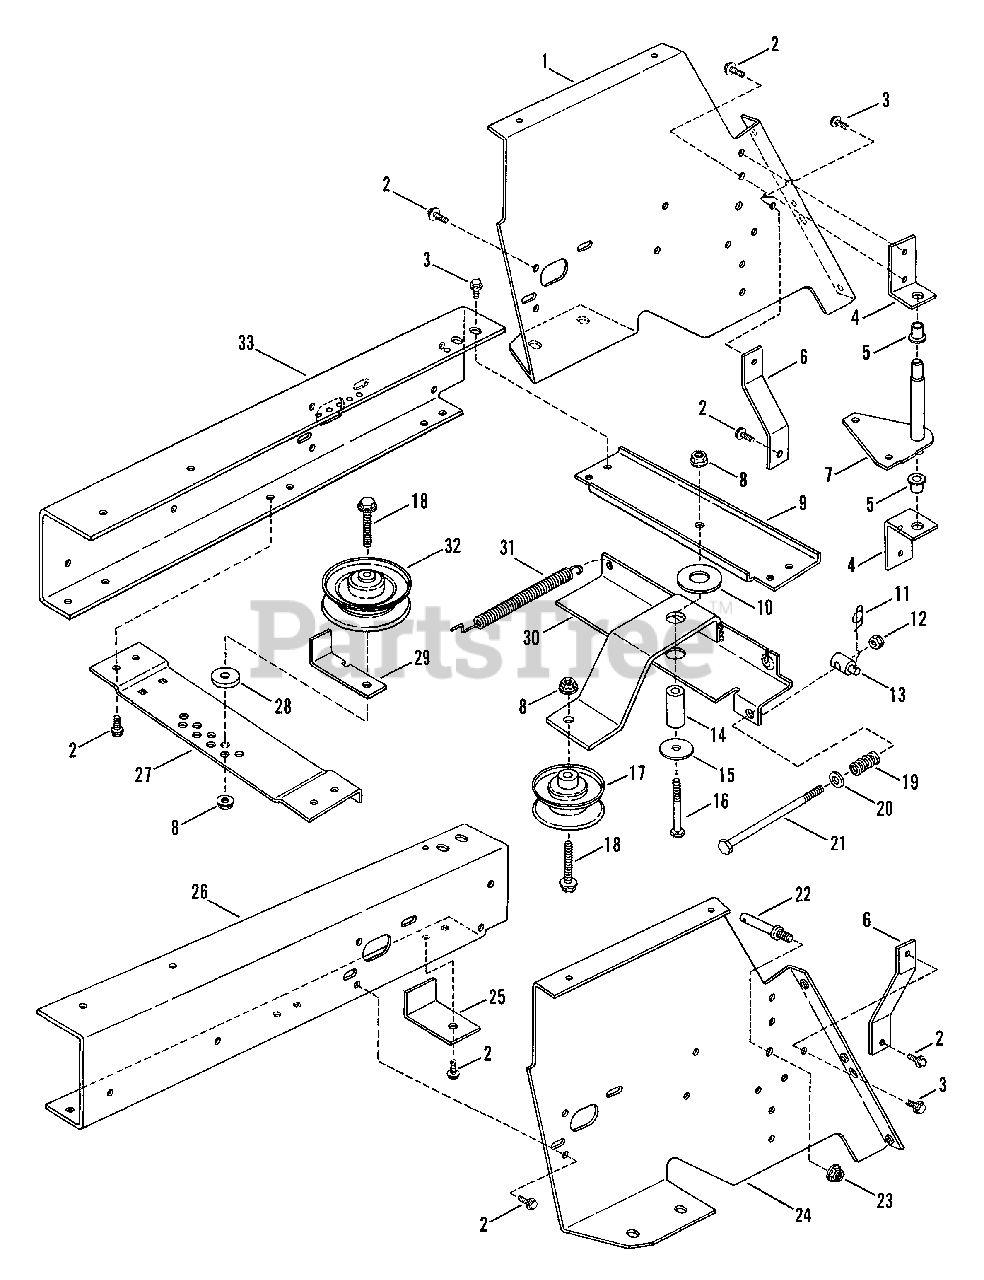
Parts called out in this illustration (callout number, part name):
1	MOUNT, Transmission (R.H.)
2	SCREW, 5/16-18 x 5/8" H.W. Self-Tapping
3	SCREW, 5/16-18 x 1/2" H.W. Self-Tapping
4	BRACKET, Bell Crank
5	BEARING
6	BRACKET, Torque
7	BELL CRANK ASSEMBLY
8	NUT, 3/8-16 Hex Flange Lock
9	CROSS BRACE, Upper
11	COTTER-PIN, 3/8 Self-Lock
12	NUT, 5/16-18 Hex Lock
13	PIN, Brake
15	WASHER, Thrust
16	BOLT, 3/8-16 x 2 1/4" Hex Head
17	PULLEY, Idler
18	BOLT, 3/8-16 x 1 3/4" Hex Flange Lock
19	SPRING
20	WASHER, 5/16 Flat
21	BOLT, 5/16-18 x 5" Hex Head
22	STUD, Idler
23	NUT, 3/8-24 Hex Flange Lock
24	MOUNT, Transmission (L.H.)
25	GUIDE, Belt
26	FRAME CHANNEL (L.H.)
27	CROSS-BRACE, Lower
29	GUIDE, Belt
30	IDLER ARM ASSEMBLY
31	SPRING, Idler
32	PULLEY, Idler
33	FRAME CHANNEL (R.H.)
